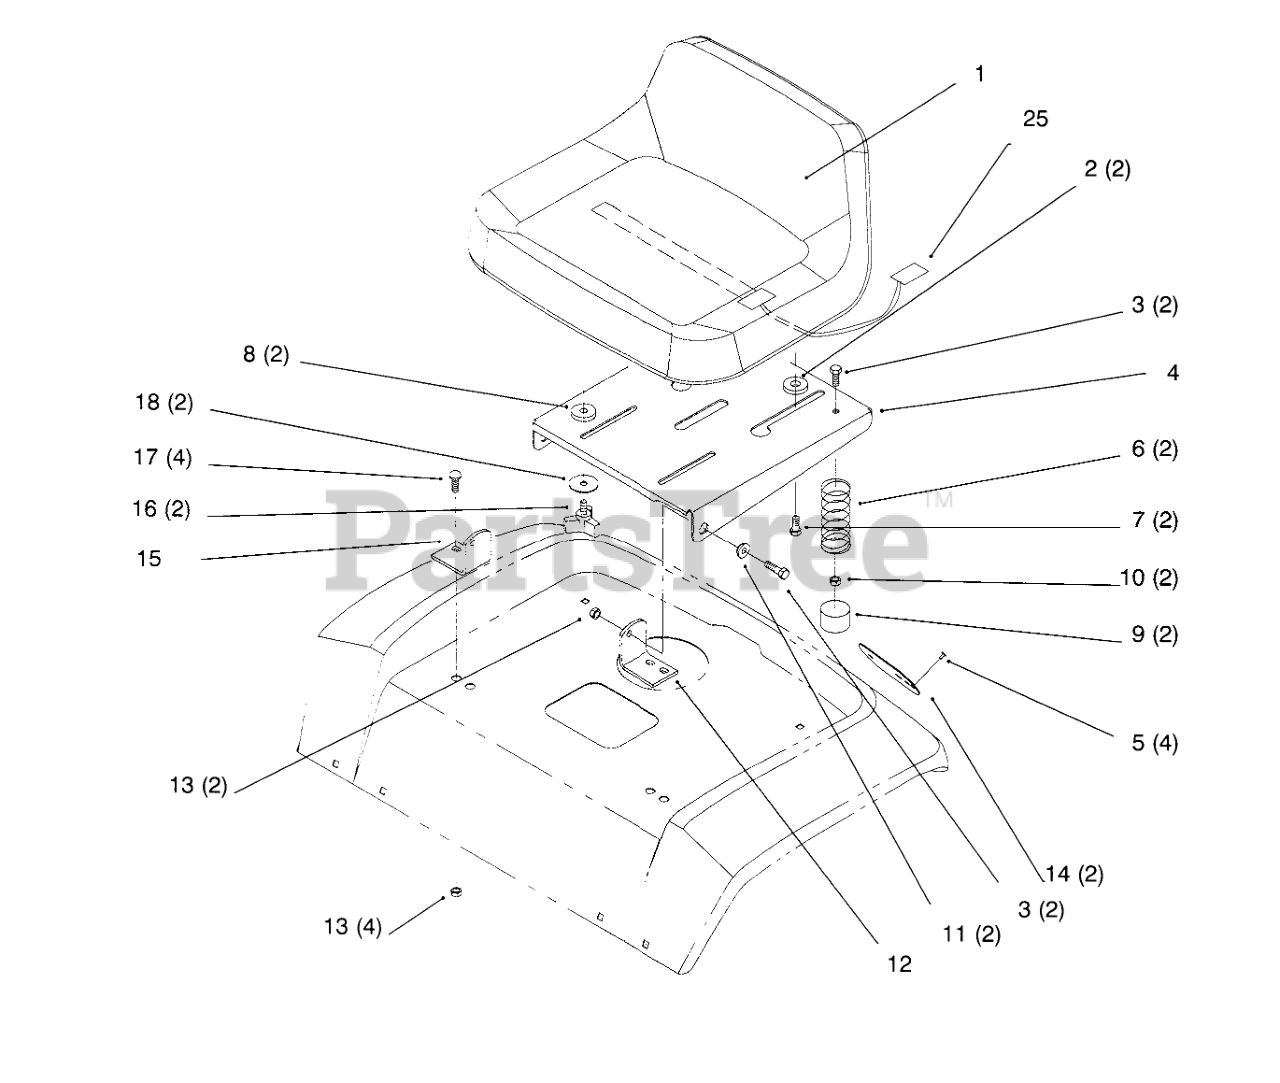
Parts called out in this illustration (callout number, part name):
1	SEAT-V-511
2	SPACER-NYLON
3	SCREW-HH
4	Support-Seat
5	RIVET-BLIND
6	SPRING-COMPRESSION
7	BOLT-SHOULDER
8	SPACER-NYLON
9	CAP-PROTECTOR
10	NUT-LOCK, NI
11	BUSHING
12	BRKT-PIVOT L.H. B
13	NUT-LOCK, NI
14	REFLECTOR-STICK ON
15	Bracket-Pivot RH
17	BOLT-CARR
18	WASHER-PIVOT
25	SWITCH-SEAT
